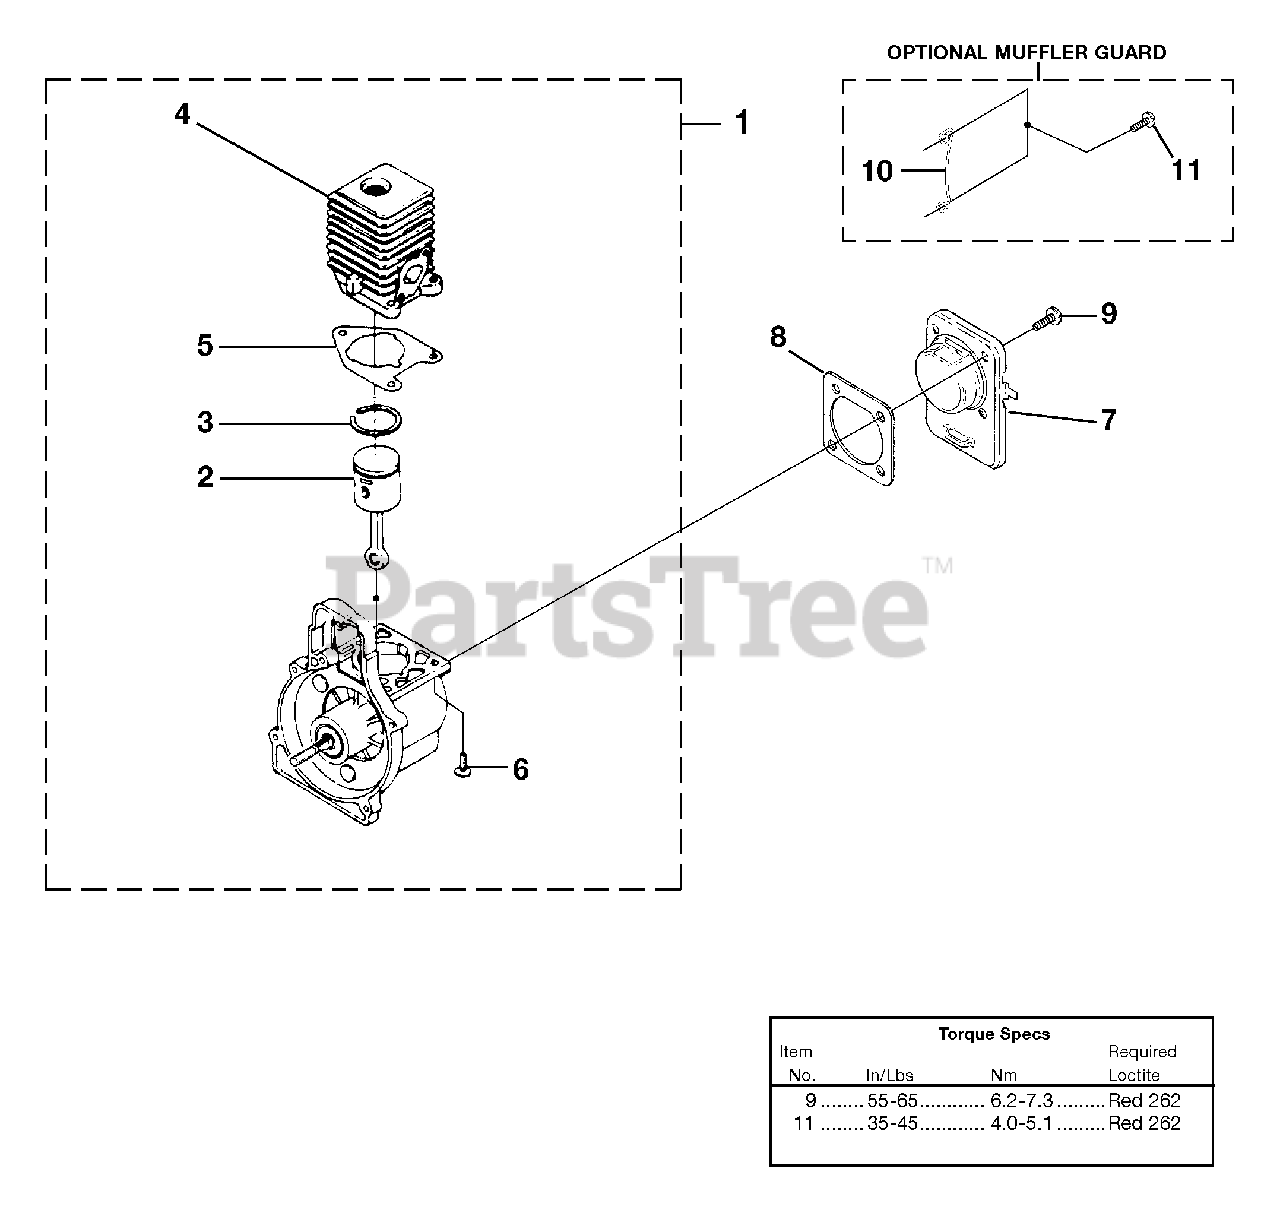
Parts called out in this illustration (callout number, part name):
1	SHORT BLOCK ASSY.
2	PISTON & ROD ASSY.
3	RING-Piston
4	CYLINDER
5	GASKET-Cylinder
6	SCREW-Sems (12-24 X 3/4")
7	CRANKCASE COVER
8	GASKET-Crankcase Cover
9	SCREW-Sems (10-24 X 1/2")
10	MUFFLER GUARD
11	SCREW-Thread Forming (10-14 X 1/2")
